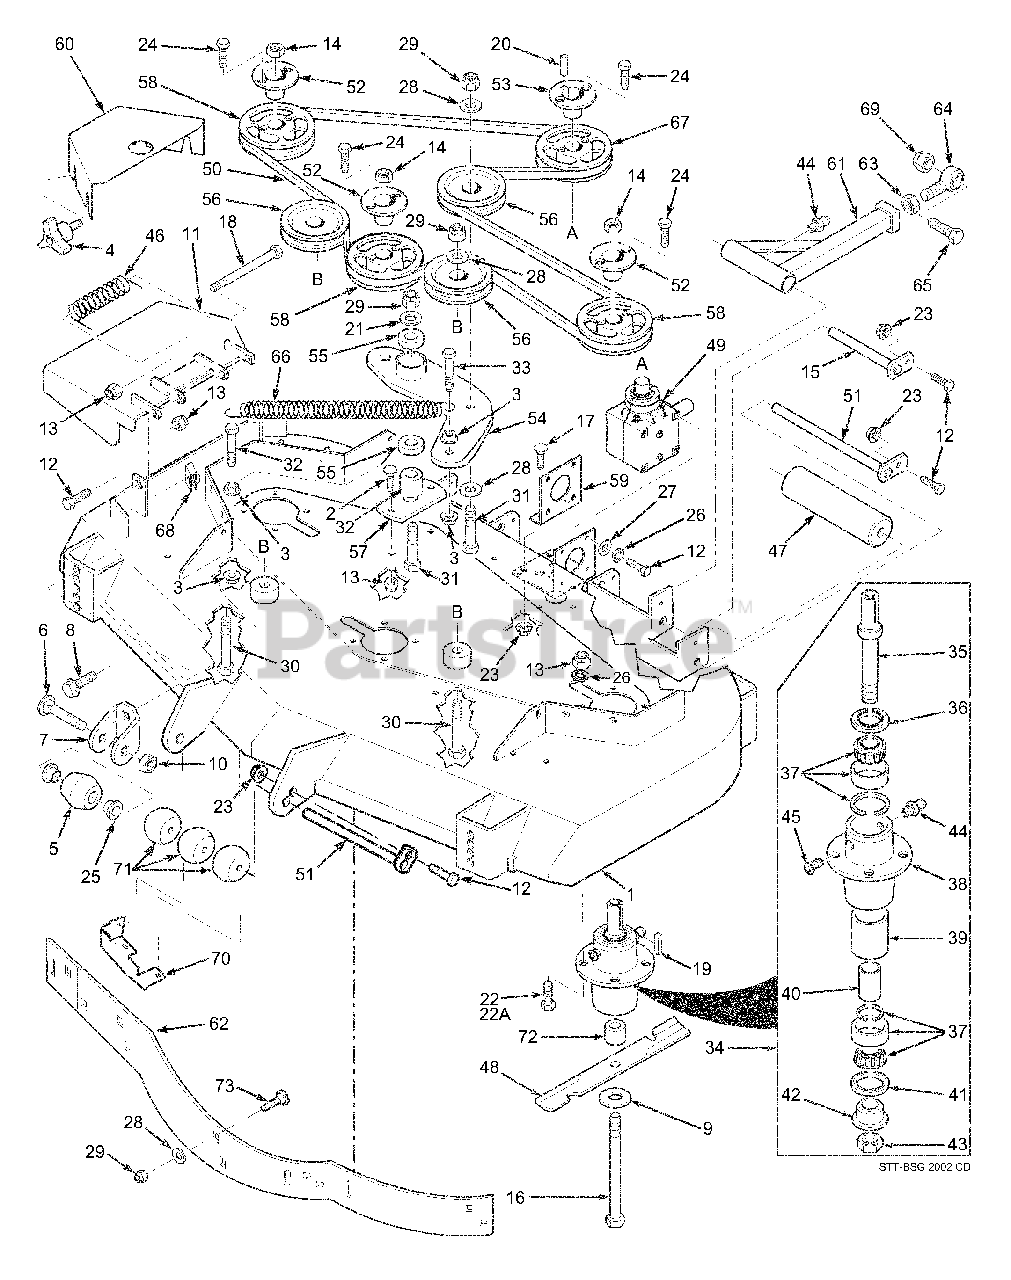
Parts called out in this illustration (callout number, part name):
1	Cutter Deck, 61" Advantage
1	Cutter Deck, 72" Advantage
2	Bolt, Carriage 5/16-18 x 1"
3	Nut, Hex Serrated Flange 3/8-16
4	Wing nut, 3/8-16
5	Anti-Scalp Wheel
6	Bolt, Carriage 3/8-16 x 4"
7	Anti-Scalp Wheel Bracket
8	Bolt, Hex Serrated Flange 3/8-16 x 1"
9	Flatwasher, 5/8" (.688 x 1.75 x .134)
10	Locknut, 3/8-16 Center Lock
11	Discharge Chute, 61" & 72" Adv.
12	Bolt, Hex Head 5/16-18 x 1.75" (Front)
13	Nut, Hex Elastic Stop 5/16-18
14	Nut, 5/8-11 UNC
15	Push Arm Shaft
16	Bolt, Hex Head 5/8-11 x 9.50"
17	Bolt, Carriage 5/16-18 x .75"
18	Bolt, Hex Head 5/16-18 x 4.75"
19	Key, 1/4 x 1/4 x 2"
20	Key, 1/4 x 1/4 x 1.25"
21	Flatwasher,3/8-.39 x .938 x .105 HD
22	Bolt, Hex Head 5/16-18 x 1.50"
22A	Bolt, Hex Head 5/16-18 x 1.75"
23	Nut, Hex Serrated Flange 5/16-18
24	Bolt, Hex Head 1/2-20 x .75"
25	Bushing, .376 I.D. Oilite
26	Lockwasher, 5/16"
27	Flatwasher, 5/16" (.375 x .875 x .083)
28	Flatwasher, 3/8" (.391 x .938 x .105)
29	Nut, Hex Elastic Stop 3/8-16
30	Bolt, Hex Head 3/8-16 x 3.25"
31	Bolt, Hex Head 3/8-16 x 2.50"
32	Pivot, Idler - Short
33	Bolt, Hex Head 3/8-16 x 1.50" Grade 8
34	Spindle Assembly
35	Spindle Shaft
36	Seal, Top
37	Bearing Assembly
38	Spindle Housing
39	Spacer, Outside
40	Spacer, Inside
41	Seal, Bottom
42	Spindle Bushing, Bottom
43	Nut, Special 1 - 1/16-18
44	Grease Fitting
45	Relief Fitting, Tapered Spindle
46	Spring, Discharge Chute
47	Guide, Roller
48	Cutter Blade, 21.0" 61"
48	Cutter Blade, 24.5" 72"
49	Gearbox Assembly, Deck Drive
50	Belt, Cutter Deck Drive, 61"
50	Belt, Cutter Deck Drive, 72"
51	Roller Shaft
52	Tapered Hub, 1-1/8" Bore
53	Tapered Hub, 1" Bore
54	Idler Arm, Cutter Deck
55	Bearings, Ball
56	Pulley, Idler
57	Base, Idler Pivot
58	Pulley, 6.35 O.D. - 61"
59	Mounting Plate, Gearbox
60	Belt Cover, LH - 61"
61	Pusharm
62	Baffle, Custom Cut 61A
63	Nut, Hex Head 5/8-18 UNF
64	Rod End, 5/8" Male RH Thread
65	Bolt, Hex Head 5/8-11 x 4-1/2"
66	Spring, Cutter Deck
67	Pulley, 6.75 O.D. - 61"
68	U-Nut, 3/8-16
69	Nut, Hex Elastic Stop 5/8-11
70	Discharge Baffle 61"
71	Guide Roller
72	Spacer, Spindle
73	Bolt, Carriage 3/8-16 x 1"
